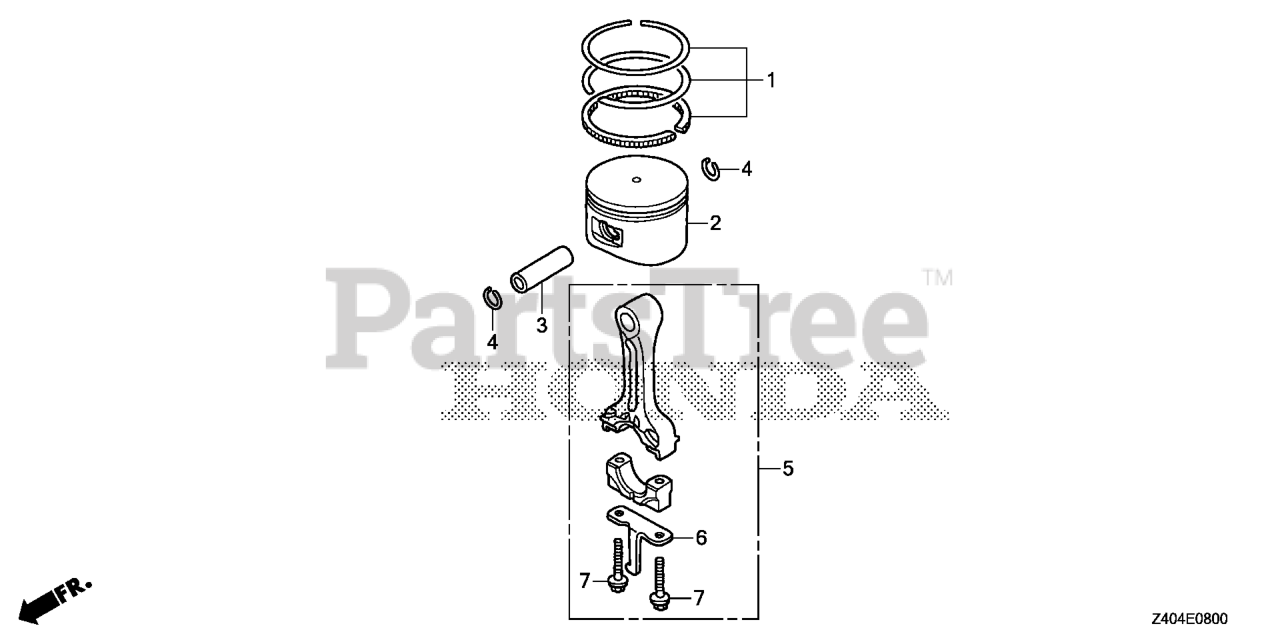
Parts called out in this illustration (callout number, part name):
1	RING SET, PISTON (STD)
2	PISTON (STD)
3	PIN, PISTON (10X33)
3	PIN, PISTON
4	CLIP, PISTON PIN (10MM)
5	ROD ASSY., CONNECTING
6	DIPPER, CONNECTING ROD
7	BOLT, CONNECTING ROD
